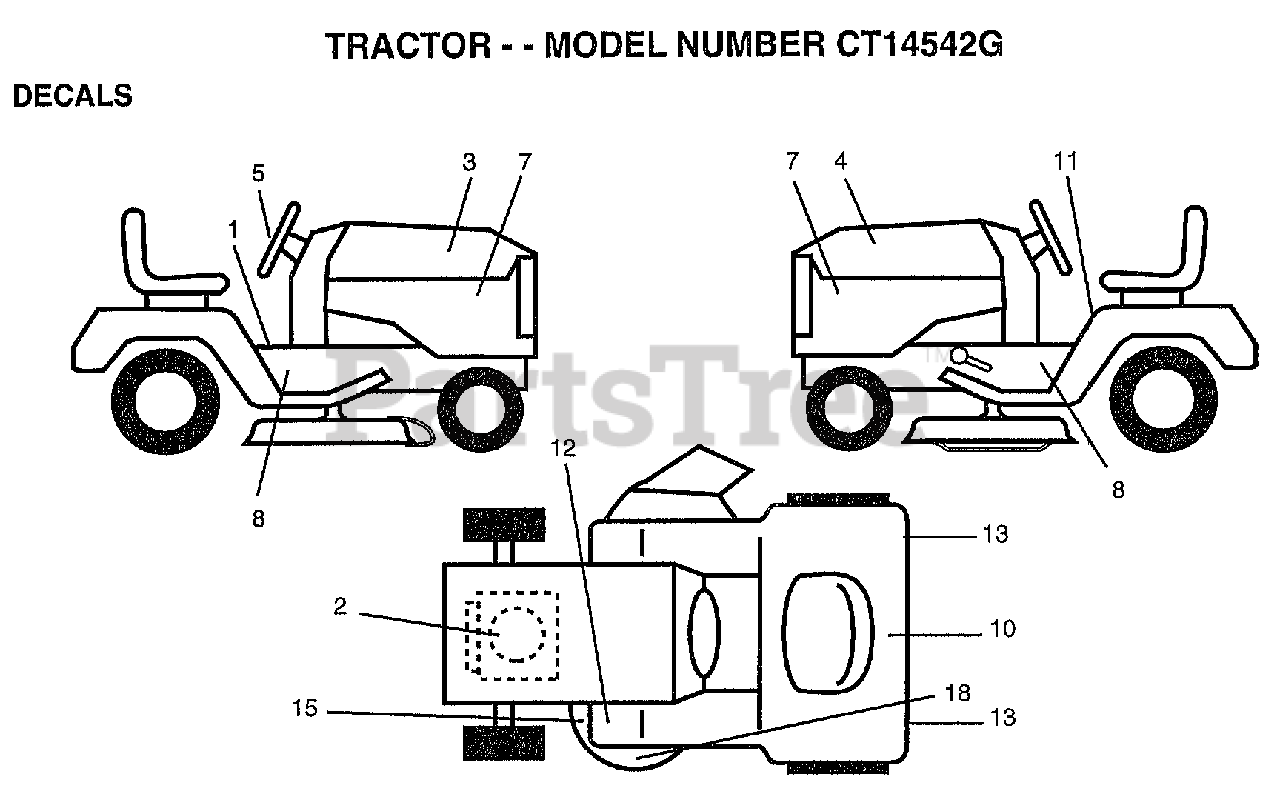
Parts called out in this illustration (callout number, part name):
1	"DECAL DASH,OPER."
2	DECAL.ENGINE
5	DECAL INST STG WH
7	DECAL SIDE PANEL
8	"DECAL CHASSIS 42"""
10	DECAL.BATRY.3-3908
11	"DECAL DANGER,FEND"
13	REFLECTOR-TAIL YT
15	"DECAL-SCHEM,BELT"
18	"DECAL,ENVIRO DECK"
